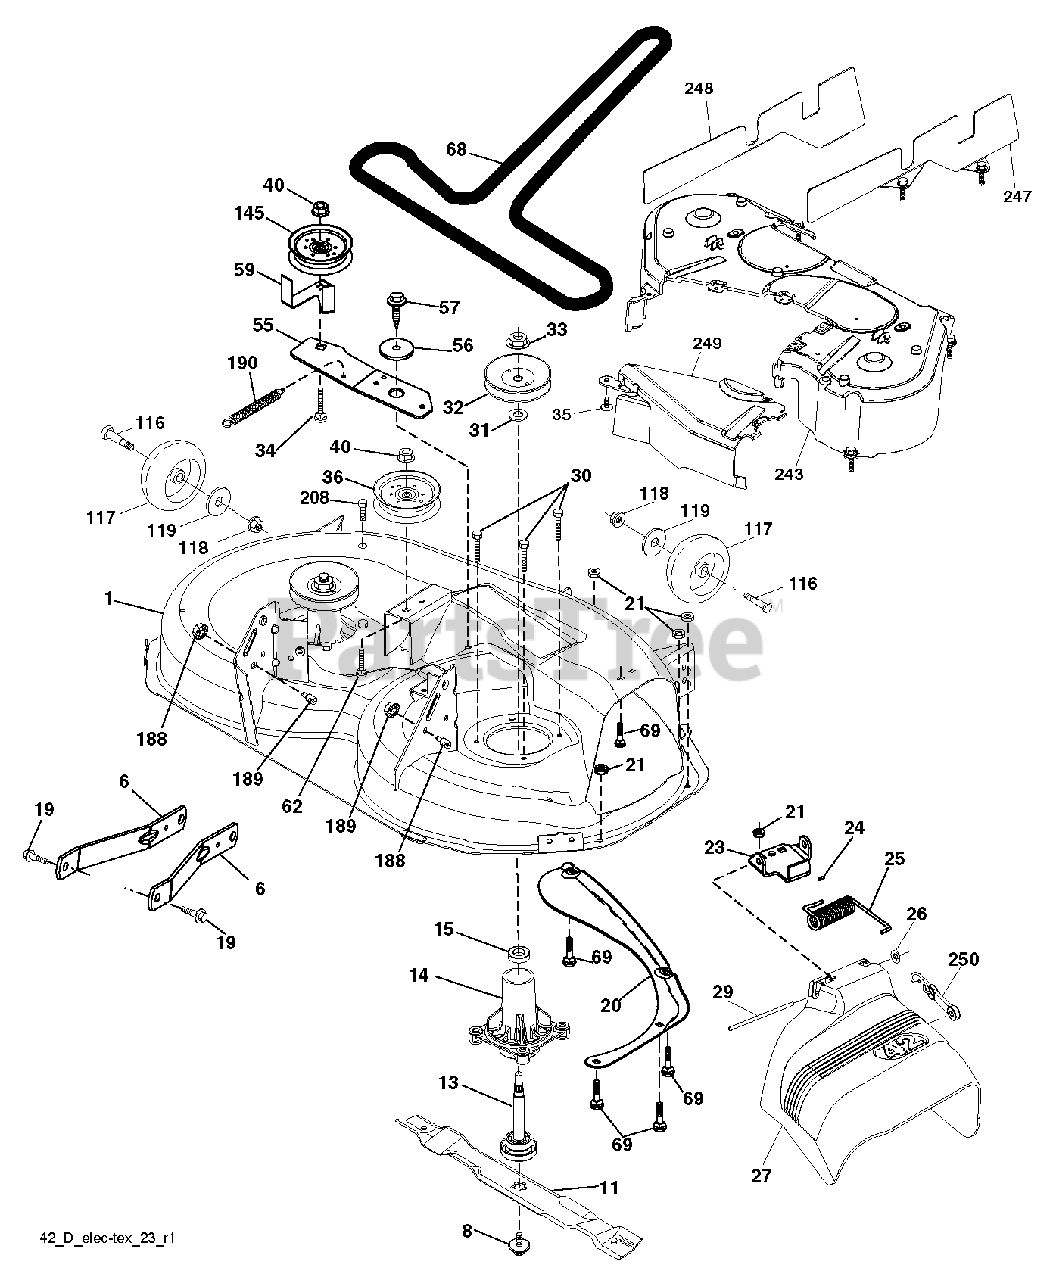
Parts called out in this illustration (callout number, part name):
1	DECK.WELDMENT.42"
6	ARM.SUSPENSION.MOWER.R
8	BOLT.WASHER.ASM.7/16-2
11	42" HI-LIFT BLADE
13	SHAFT.ASM.MDRL.N/GREASE.38
14	HOUSING MANDREL
19	BOLT.SHOULDER
20	BAFFLE.VORTEX
21	LOCKNUT
23	BRKT.DEFLECTOR.38"2005+
24	CAP-SLEEVE LT
25	SPRING.TORSION.DEFLECT
26	NUT PUSH M
29	ROD.HINGE
30	SCREW, WASHER HEAD
31	WASHER.SPACER.MANDREL
32	PULLEY/MANDREL
33	NUT.FLANGE.LOCK.TOP
34	BOLT
35	FASTENER.XMAS.TREE
36	PULLEY.IDLER.2006
40	NUT LOCK FLG 3/8-16 UNC
55	IDLER.ARM.42"
56	SPACER.RETAINER
57	SCREW 3/8-16X1
59	GUARD, BELT
62	BOLT.3/8-16X1.50
68	BELT V SECONDARY
69	BOLT
117	WHEEL.GAGE.HALF.SPOKED
118	NUT LOCK FLG 3/8-16 UNC
119	WASHER
145	PULLEY.IDLER.48"PRIMARY
188	STUD.FASTNER.W/ANTI-ROTATE
189	NUT LOCK HEX FLANGE 5/16-18
190	SPRING.MOWER.DRIVE.ELECTRIC
208	SCREW 3/8-16X1/2
